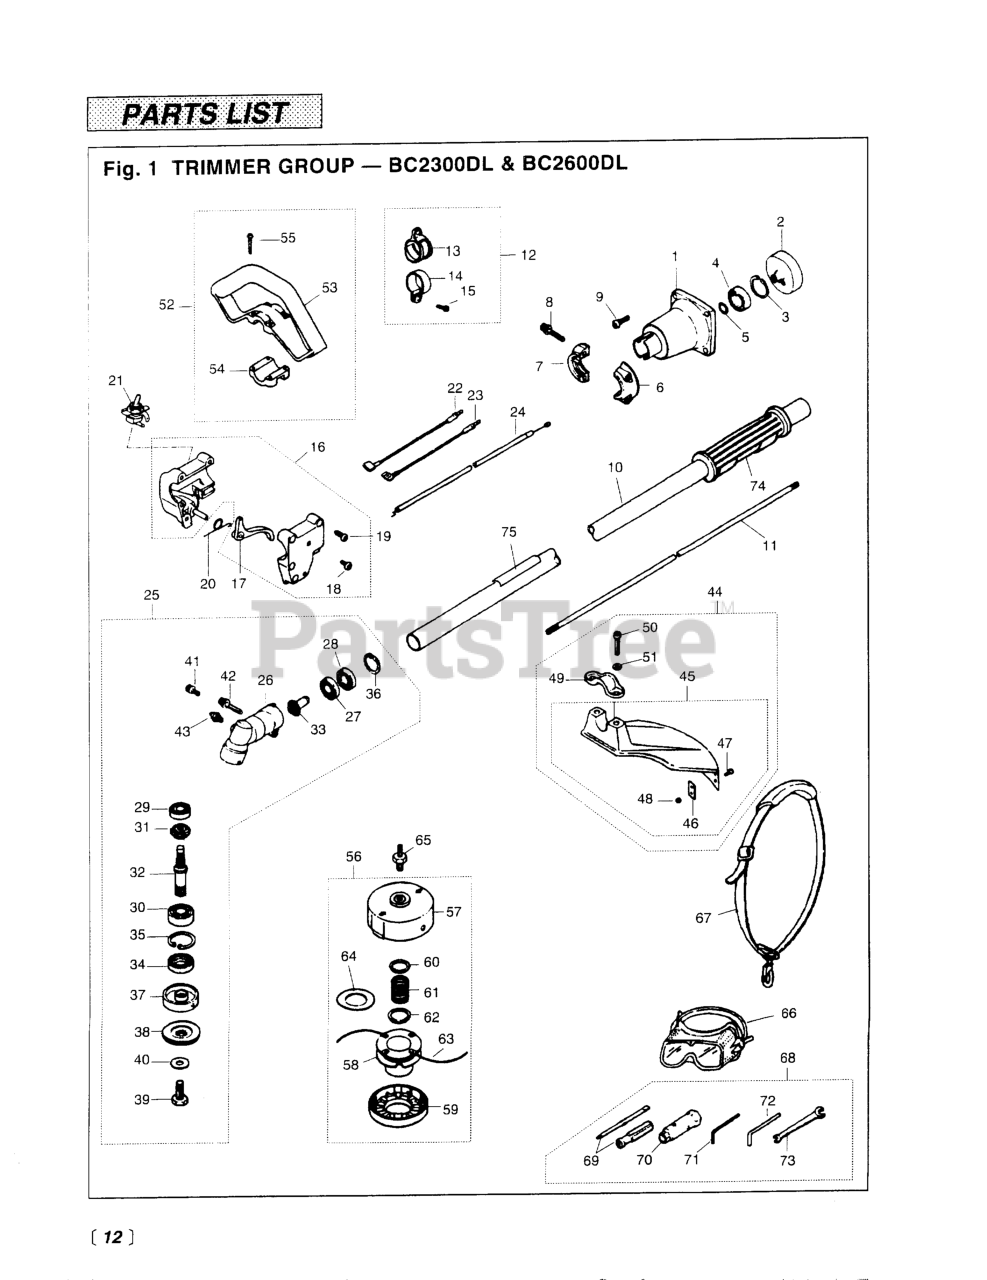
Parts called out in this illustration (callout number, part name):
3	RING, SNAP, M28 x 1.2
4	BEARING
6	CLAMP, LEFT
7	CLAMP, RIGHT
8	BOLT
9	BOLT, M6 x 20
12	HANGER COMPLETE
13	HANGER
14	CLAMP
15	SCREW, M5 x 25
17	LEVER, THROTTLE
18	SET SCREW, ANTI-ROTATION
19	SCREW
20	SPRING, THROTTLE TRIGGER
21	SWITCH, STOP
22	CORD, RED (LEAD WIRE)
23	CORD, BLACK (LEAD WIRE)
24	CABLE COMP (RPLS 6460- )
25	GEARCASE ASSEMBLY
26	GEARCASE
27	BEARING
28	BEARING
29	BEARING
30	BEARING
31	GEAR
33	PINION
34	SEAL, OIL
35	RING, SNAP
36	RING, SNAP
37	HOLDER (A)
38	HOLDER (B)
40	WASHER
41	BOLT, M5 x 12
42	BOLT, M5 X 25
43	FITTING, GREASE
44	GUARD ASSEMBLY
46	BLADE
47	SCREW, M5 x 12
48	NUT
49	CLAMP
50	BOLT, M6 x 1.30
51	WASHER, M6 X 15
52	HANDLE ASSEMBLY
53	HANDLE
54	CLAMP
55	SCREW, M5 x 35
56	4
60	PLATE, LARGE
62	PLATE, SMALL
63	CORD
64	SPACER
65	ARBOR, 8MM
66	GOGGLE
67	SHOULDER STRAP ASSY
68	TOOL SET
69	SCREWDRIVER
71	WRENCH (TOOL)
72	BAR
73	SPANNER, 8 X 10 (RPLS 2540- )
75	LABEL, BC2300/2600DL
